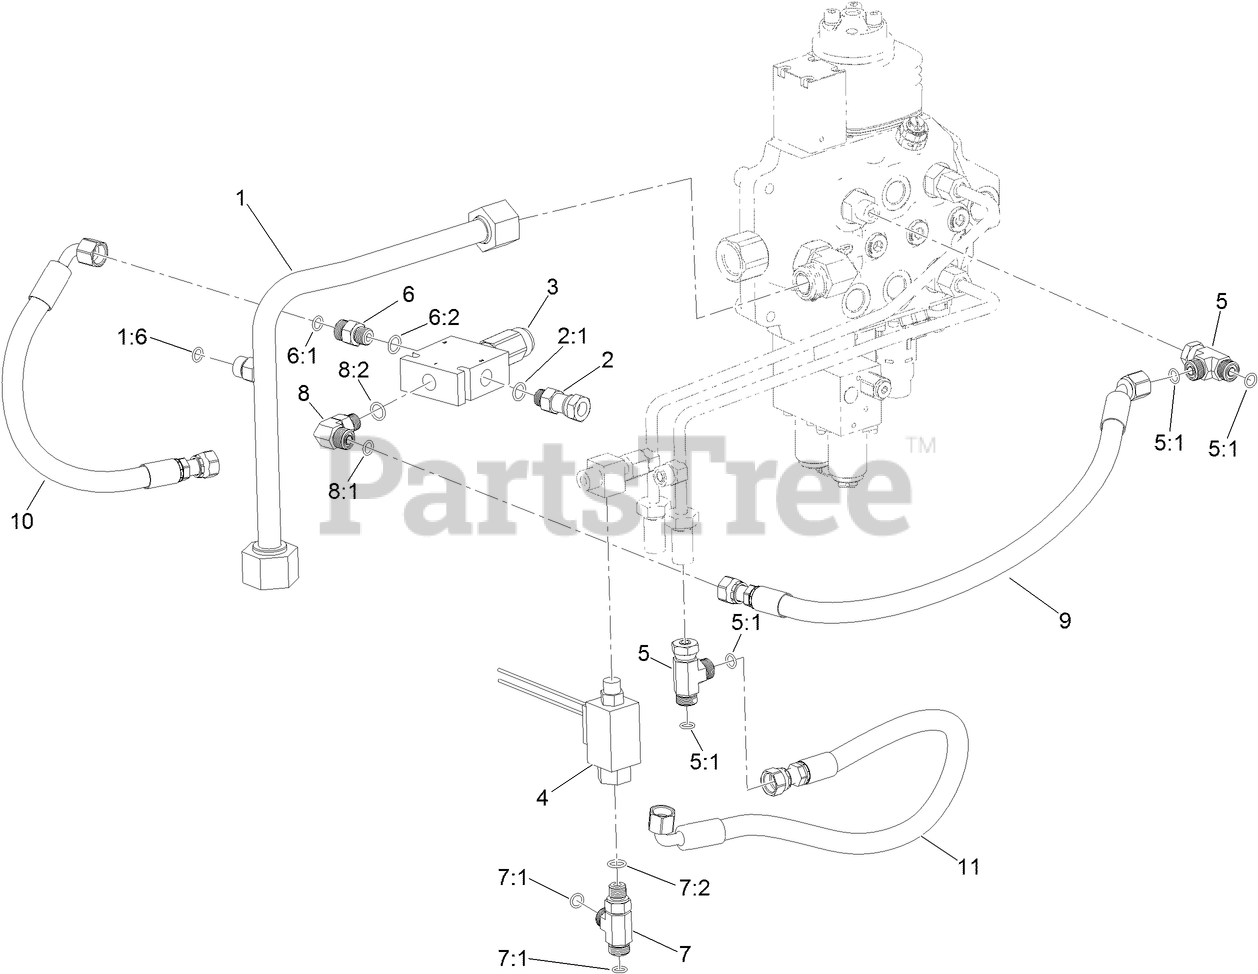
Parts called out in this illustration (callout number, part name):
1	HYD TUBE ASM
1:6	O-RING
2	CONNECTOR-SWIVEL, STRAIGHT
2:1	O-RING
3	VALVE-SEQUENCE
4	SWITCH-PRESSURE,
5	FITTING-TEE, SWIVEL NUT
5:1	O-RING
6	FITTING-STRAIGHT
6:1	O-RING
6:2	O-RING
7	FITTING-TEE
7:1	O-RING
7:2	O-RING
8	FITTING-ELBOW, 90 DEG
8:1	O-RING
8:2	O-RING
9	HOSE-HYD
10	HOSE ASM
11	HOSE-HYD
